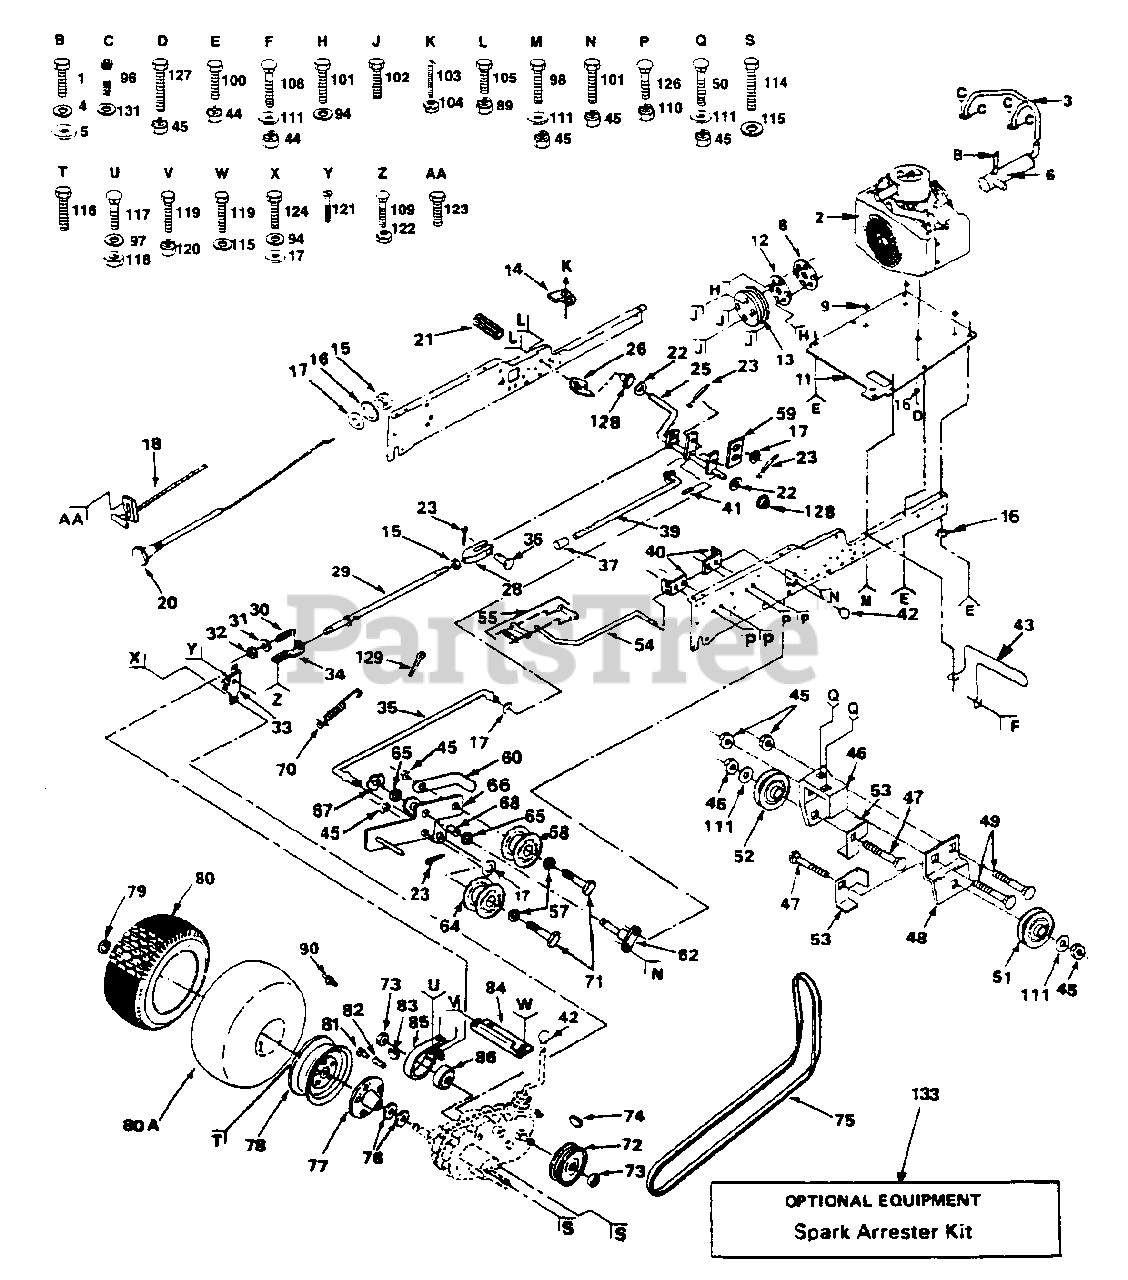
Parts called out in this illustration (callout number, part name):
1	Bolt, Hex Fin 1/4-20 x 3/4
3	Tube Assembly, Exhaust
4	Washer, Lock Hvy Helical 1/4
5	Washer 9/32 x 3/4 x 12 Gauge
6	Muffler, Exhaust
13	Pulley, Ground Drive
14	Actuator, Switch, Interlock
15	Nut, Hex 3/8-24
16	Washer, Lock Ext. Tooth 3/8
17	Washer 13/32 x 13/16 x 16 Gauge
18	Control, Throttle
20	Control, Choke
22	Washer 25/32 x 1-1/4 x 16 Gauge
23	Pin, Cotter 3/32 x 3/4
25	Shaft, Foot Pedal
26	Bracket, Interlock
30	Spring, Compression
31	Washer 13/32 x 1 x 14 Gauge
32	Nut, Crownlock 3/8-24
33	Bracket, Brake
34	Guide, Rod, Brake
39	Rod, Parking Brake
40	Bracket, Rod, Shift
41	Pin, Roll 3/16 x 1-1/4
42	Knob
43	Muffler, Guard
44	Nut, Lock Hex W/Inss. 3/8-16
45	Nut, Crownlock 3/8-16
46	Bracket, V-Pulley, Drive, Mule
47	Bolt, Carriage 3/8-16 x 1-3/4
48	Bracket, Idler, Flat
49	Bolt, Carriage 3/8-16 x 1
50	Bolt, Carriage 3/8-16 x 3/4
52	Pulley, Idler
54	Rod, Shift, Hi - Lo
55	Clip, Connecting Link, Spring
57	Washer 13/32 x 7/8 x 13 Gauge
58	Idler, Flat
59	Retainer, Spring
60	Retainer, Belt
62	Bracket Assembly, Clutch
64	Idler, Grooved
65	Washer, Hardened
66	Bracket, Clutch W/Bearing (Incl. Key No. 68)
68	Bearing, Idler
70	Spring, Extension
71	Bolt, Hex 3/8-16 x 1-3/4
72	Pulley, Transaxle
73	Locknut 1/2-20
74	Key, Woodruff 3/16 x 5/8
76	Washer, Thrust, Axle
77	Bushing, Assembly and Wheel Hub
78	Assembly, Rim Rear
80	Tire, Rear
80A	Tube, Rear (Optional, Service Item Only)
83	Key, Woodruff #9 (3/16 x 3/4)
84	Bracket, Support, Transaxle
89	Nut, Lock w/Ins. 1/4-20
90	Fitting, Grease
94	Washer, Lock 3/8
96	Screw, Hex Socket Hd. 5/16-16 x 3/4
97	Washer, Lock 1/4
98	Bolt, Hex 3/8-16 x 1-1/4 Grade 5
100	Bolt, Hex 3/8-16 x 1
101	Bolt, Hex Head 3/8-16 x 1 Grade 5
102	Screw, Hex 5/16-18 x 1
103	Screw, Fin #10-24 x 1
104	Locknut #10-24
105	Bolt, Hex Head 1/4-20 x 3/4
108	Bolt, Carriage 3/8-16 x 1 Grade 5
109	Bolt, Carriage 5/16-18 x 3/4
110	Nut, Lock Hex W/Ins. 5/16-18
111	Washer 13/32 x 1 x 12 Gauge
114	Bolt, Hex 7/16-14 x 1-1/4
115	Washer, Lock 7/16
117	Bolt, Carriage 1/4-20 x 5/8
118	Nut, Hex 1/4-20
119	Bolt, Hex 7/16-14 x 1
120	Nut, Crownlock 7/16-14
121	Screw, Mach. Udrcut. Flat Head 3/8-16 x 3/4
122	Locknut 5/16-18
123	Screw, Hex 1/4-20 x 1/2
124	Bolt, Hex 3/8-16 x 7/8
126	Bolt, Carriage 5/16-18 x 3/4
127	Bolt, Hex 3/8-16 UNC x 1-1/2
128	Nyliner
129	Pin, Cotter 1/4 x 1
131	Washer, Lock 5/16
133	Kit, Arrester, Spark
